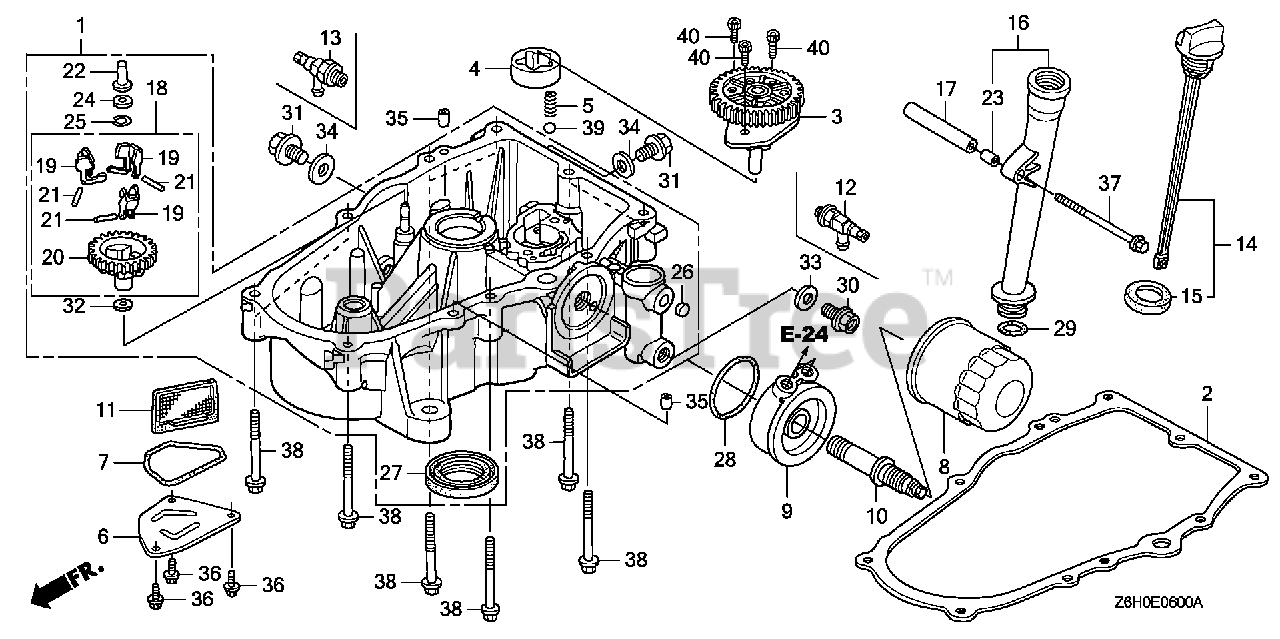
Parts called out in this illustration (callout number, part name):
1	PAN ASSY., OIL
2	GASKET, CASE COVER
3	COVER ASSY., OIL PUMP (THREE BOLTS)
4	ROTOR, OIL PUMP (OUTER)
5	SPRING, RELIEF VALVE
6	PLATE, OIL FILTER
7	O-RING, OIL PLATE
8	FILTER, OIL (FILTECH TOYO ROKI) (SOLD INDIVIDUALLY)
8	FILTER, OIL (TOYO ROKI) (SOLD INDIVIDUALLY)
9	BASE, OIL FILTER
10	BOLT, OIL FILTER
11	SCREEN, OIL FILTER
12	VALVE, DRAIN (14X1.5)
13	VALVE, OIL SHUT-OFF
14	CAP ASSY., OIL FILLER
15	GASKET, OIL FILLER CAP
16	EXTENSION, OIL FILLER
17	COLLAR, FILLER SETTING
18	GOVERNOR ASSY.
19	WEIGHT, GOVERNOR
20	HOLDER, GOVERNOR WEIGHT
21	PIN, GOVERNOR WEIGHT
22	SLIDER, GOVERNOR
23	COLLAR, EXTENSION
24	WASHER (6X16)
25	CLIP, GOVERNOR HOLDER
26	PLUG, SEALING (10MM)
27	OIL SEAL (38X58X9)
28	O-RING (51.6X2.3) (ARAI)
29	O-RING (22.1X2.2)
30	BOLT, DRAIN PLUG (14MM)
31	BOLT, DRAIN PLUG (20MM)
32	WASHER, PLAIN (6MM)
33	WASHER, DRAIN PLUG (14MM)
34	WASHER, DRAIN PLUG (20MM)
35	PIN, DOWEL (8X14)
36	BOLT, FLANGE (6X14)
37	BOLT, FLANGE (6X100)
38	BOLT, FLANGE (8X50)
39	BALL, STEEL (#12) (3/8)
40	BOLT, SOCKET (6X16)
